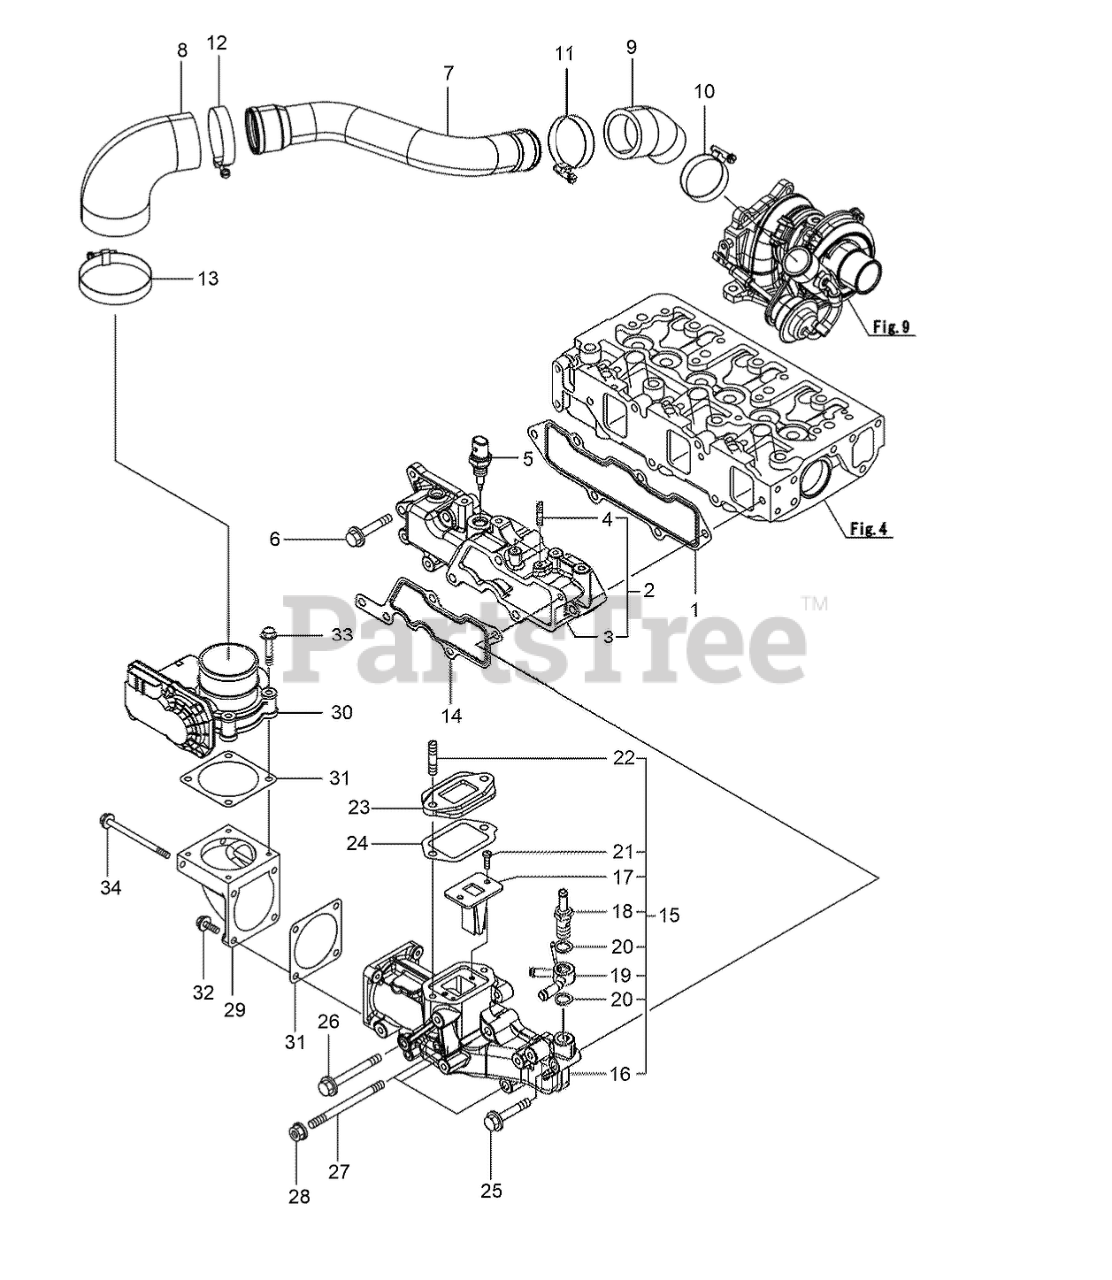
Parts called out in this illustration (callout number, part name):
1	GASKET-MANIFOLD, INTAKE
2	INTAKE MANIFOLD ASM
3	MANIFOLD-INTAKE, AIR
5	SENSOR-TEMPERATURE, AIR
7	DUCT SUCTION
8	JOINT-RUBBER
9	JOINT, RUBBER
10	CLAMP-HOSE
11	CLAMP-HOSE
12	CLAMP-HOSE
13	CLAMP-HOSE
14	GASKET-COLLECTOR
15	INTAKE COLLECTOR ASM
16	COLLECTOR-INTAKE
17	VALVE-REED
18	JOINT-HOSE
19	Joint-Hose
20	Washer-Seal
22	STUD, M8X 35
23	SPACER-VALVE, E G R
24	GASKET-E G R
29	Bend-Inlet
30	BODY-THROTTLE
31	GASKET-THROTTLE
